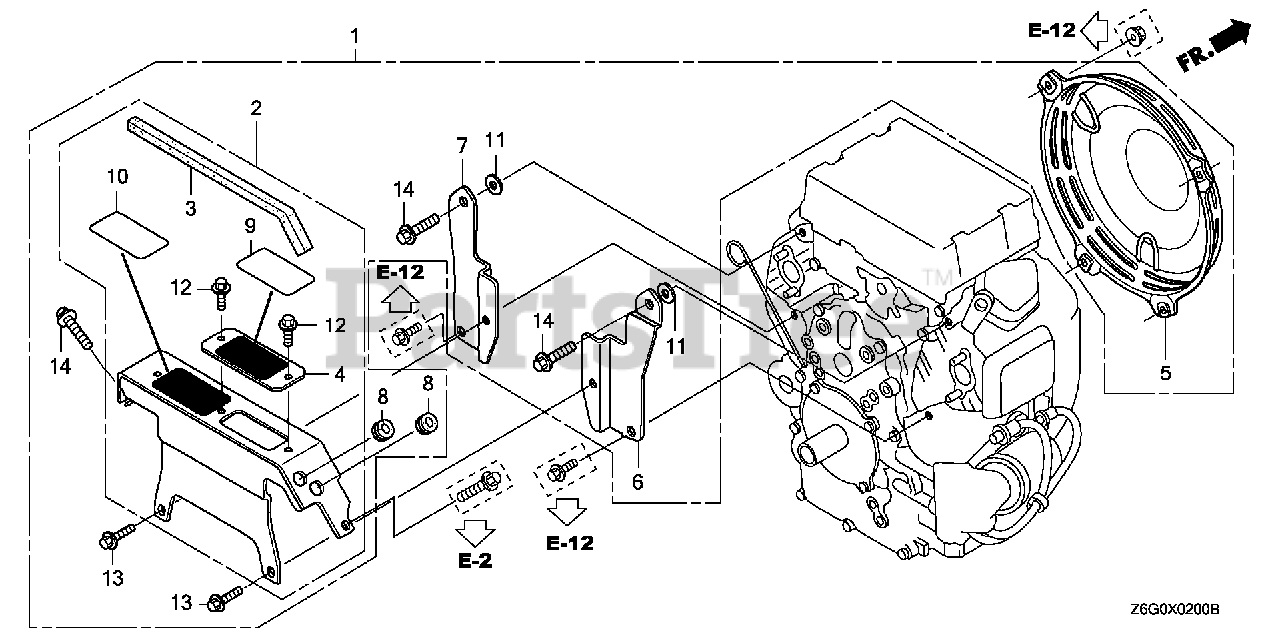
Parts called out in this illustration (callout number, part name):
1	KIT, WINTER
2	COVER ASSY., CONTROL
3	SEAL, CONTROL COVER
4	COVER B, CONTROL
5	PROTECTOR, FAN COVER
6	BRACKET, R. SHROUD
7	BRACKET, L. SHROUD
8	RUBBER, SEAT LOCK BAR CUSHION
9	LABEL, OPERATOR NOTICE (E)
10	LABEL, OPERATOR NOTICE (F)
11	WASHER, PLAIN (8MM)
12	BOLT, FLANGE (6X12)
13	BOLT, FLANGE (6X16)
14	BOLT, FLANGE (8X20)
